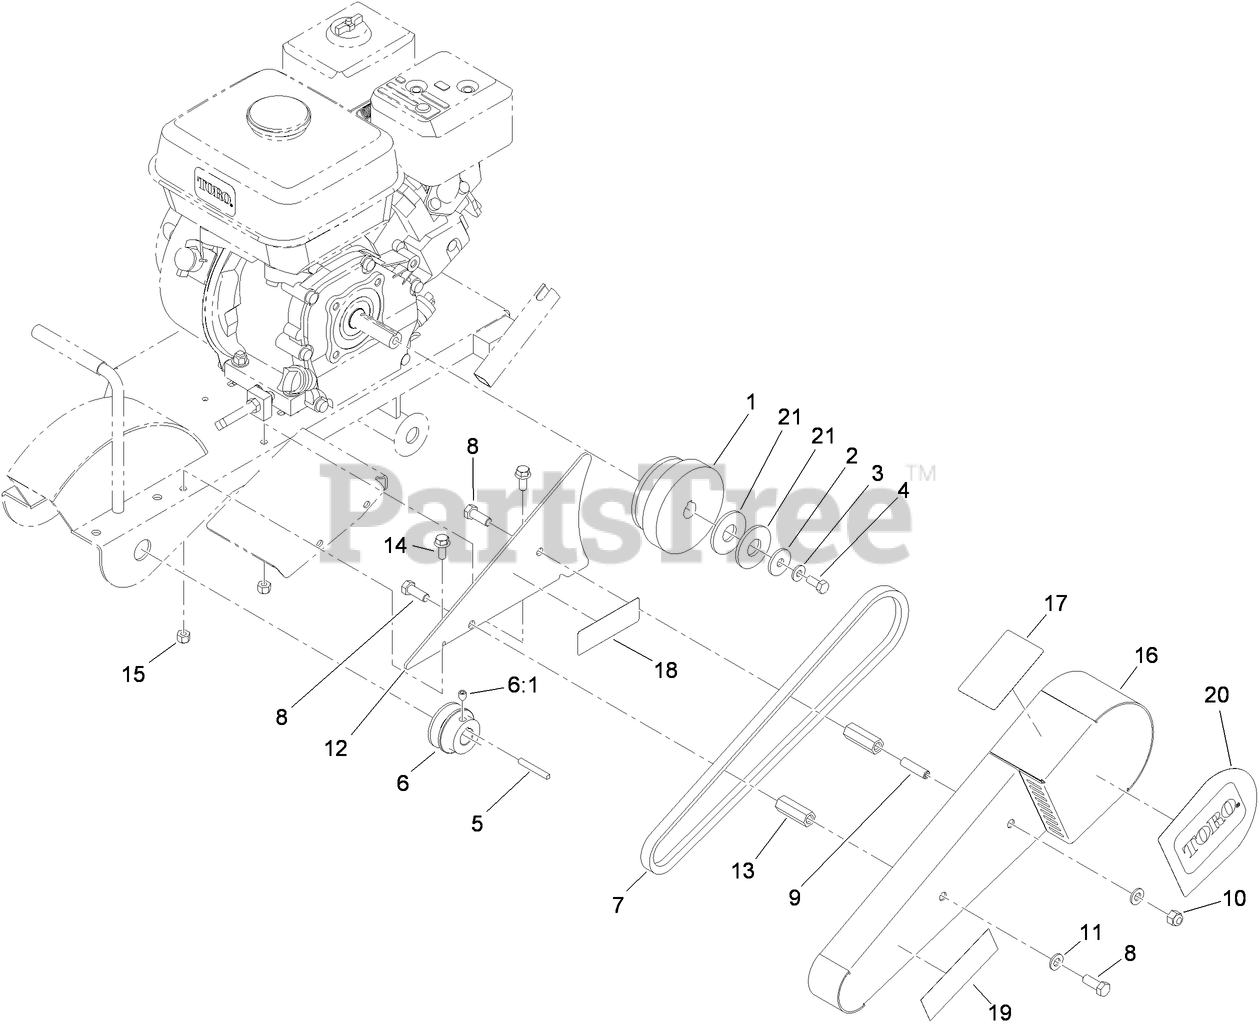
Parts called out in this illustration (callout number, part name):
1	CLUTCH-CENTRIFUGAL
2	WASHER
3	WASHER-FLAT
4	SCREW-HH
5	KEY-SQUARE
6	PULLEY-FRONT
6:1	SCREW-HSH
7	BELT-DRIVE
8	SCREW-HH
9	SCREW-SET, HSH
10	NUT-LOCK, NI
11	WASHER-FLAT
12	PLATE-GUARD, INNER
13	SPACER-GUARD, BELT
14	SCREW-HHF
15	NUT-LOCK, NI
16	OUTER BELT GUARD ASM
17	DECAL-CAUTION
18	DECAL-WARNING, SHIELDS
21	WASHER-FLAT
